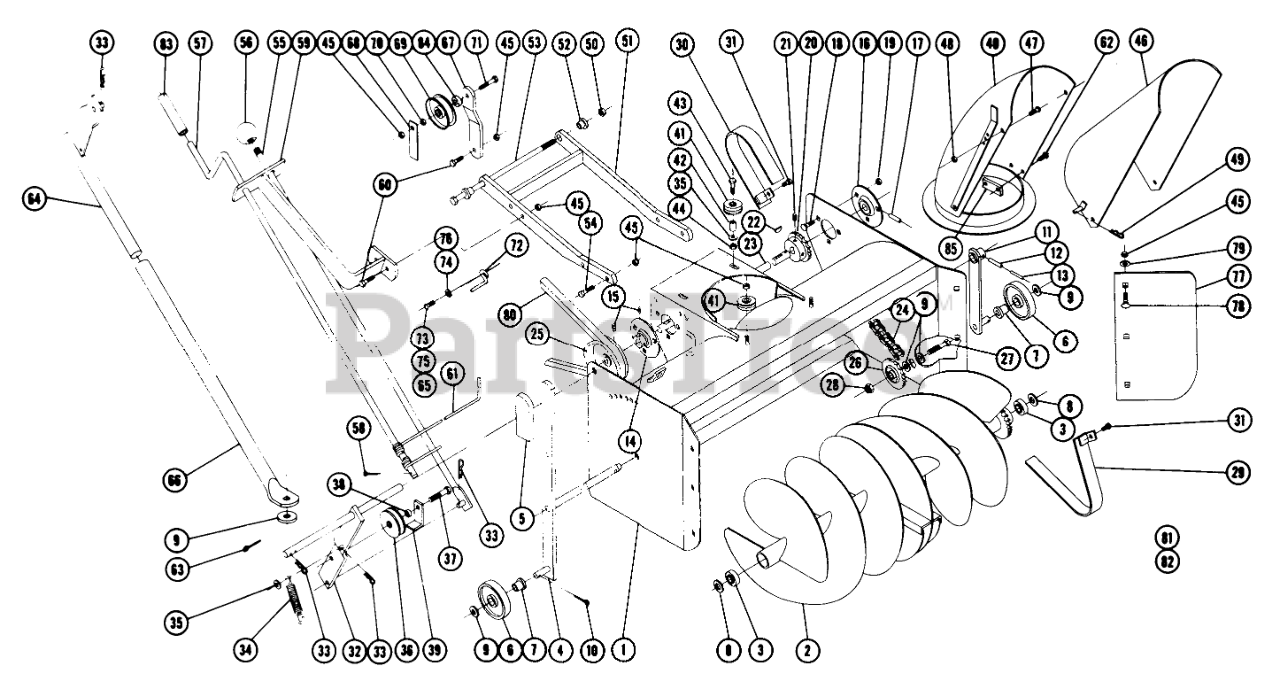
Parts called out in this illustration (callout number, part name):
1	Ass-y Wrapper
2	Auger
3	Bearing
4	Ass-y. Auger Shaft
5	GRIP
6	Wheel
7	Bushing
8	WASHER
9	Washer
10	Cotter Pin
11	Wheel Support
12	ROLL PIN 1/4 X 1-1/4
13	Roll Pin 5/32 x 1/4
14	Bearing-Flanged
15	Set Screw
16	Bearing Flanged
17	PIN-ROLL, SPIROL
18	Bolt Hex 5/16-18 x 3/4
19	Nut-Nylok
20	SPROCKET
21	Set Screw Nylok
22	Key
23	Shaft Drive
24	Chain
25	Pulley Drive Shaft
26	Idler Sprocket
27	Bolt-1/2-13-1 3/4
28	Locknut-1/2-13
29	Ass-y Guard-Inner
30	Guard-Outer
31	SCREW
32	Ass-y Idler Bracket
33	Hairpin
34	SPRING R
35	Washer
36	Pulley
37	Bolt 3/8-16 x 1 1/4 Nylok
38	BUSHING
39	Clip - Belt
40	S/A SHROUD R
41	Roller
42	SPACER
43	Bolt 1/4 20 x 1 1/4
44	Nut-Nylok
46	Deflector
47	Bolt Rd. Hd. 1/4-20 x 1/2
48	Nut, 1/4-20
49	Hairpin
51	Ass-y Mounting Frame
52	Spacer
53	Bolt-Hex. 3/8-16 x 8 1/2
54	Bolt 3/8-16 x 7/8
55	Ass-y Rod-Clutch
56	Knob
57	Crank
58	Cotter Pin
59	Control Guide Bracket
60	Bolt 3/8-16 x 1
61	Cable
62	Screw #10-16 x 1/2 Self Tap
63	Cotter Pin 3/16 x 1
64	Lid Rod
65	Screw Round Hd. 5/6-18 x 3/4 (Kohler 10 H.P.)
66	Lift Tube
67	Bracket-Idler
68	Bar Belt Guide
69	IDLER PULLEY
70	3/8-16 Jam Nut
71	Bolt 3/8-16 x 2 1/4
72	Belt Retainer
73	Bolt Round Head 5/16-24 x 3/4
74	Lockwasher
75	Screw 1/8-16 x 3/4
76	Lockwasher
77	Plate-Side Extension
78	Bolt 3/8-16 x 1
79	Washer
80	V-BELT
81	Decal-Caution
82	Decal
83	Tube
84	SPACER
85	Speed Nut (Double)
